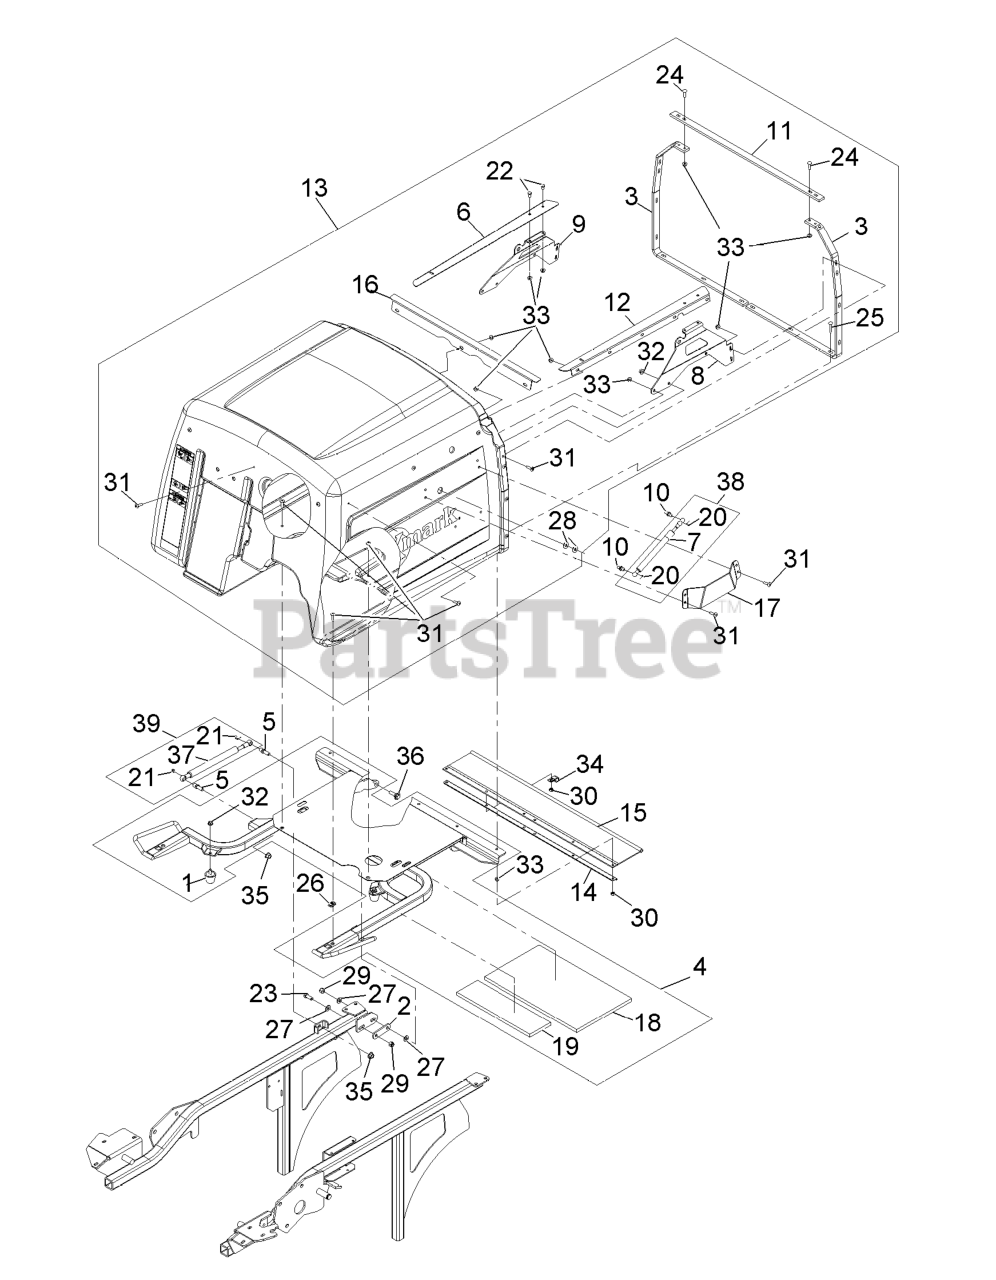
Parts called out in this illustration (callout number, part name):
1	BUMPER-RUBBER
2	ARM-LIFT, DECK
3	REINFORCEMENT-HOPPER
4	HOPPER FRAME ASM
5	STUD-BALL
6	ANGLE-SCREEN TRACK, RH
7	SHOCK-GAS TENSION
8	BRACE-DOOR PIVOT, LH
9	BRACE-DOOR PIVOT, RH
10	STUD-BALL
11	BRACKET-FRAME CONNECT
12	ANGLE-SCREEN TRACK, LH
13	ASM,HOPPER
14	CHANNEL-FRAME, HOPPER
15	DEFLECTOR-GRASS
16	CHANNEL-SCREEN, FRONT
17	PLATE-GUARD
18	INSULATION-FOAM PAD, REAR
19	INSULATION-FOAM PAD, FRON
20	CLIP-RETAINER
21	CLIP-RETAINER
22	SCREW-HH
23	SCREW-HH
24	SCREW-CARR
25	SCREW-CARR
26	Nut-Retainer-Panel 1/4-20
27	WASHER-FLAT
28	WASHER-FLAT
29	NUT-LOCK, NI
30	NUT-LOCK, NI
31	SCREW-TTH
34	CLIP-LOOM
36	SCREW-SHOULDER, HWH
37	SHOCK-COMPRESSION, GAS
38	DAMPER KIT
39	DAMPER KIT
